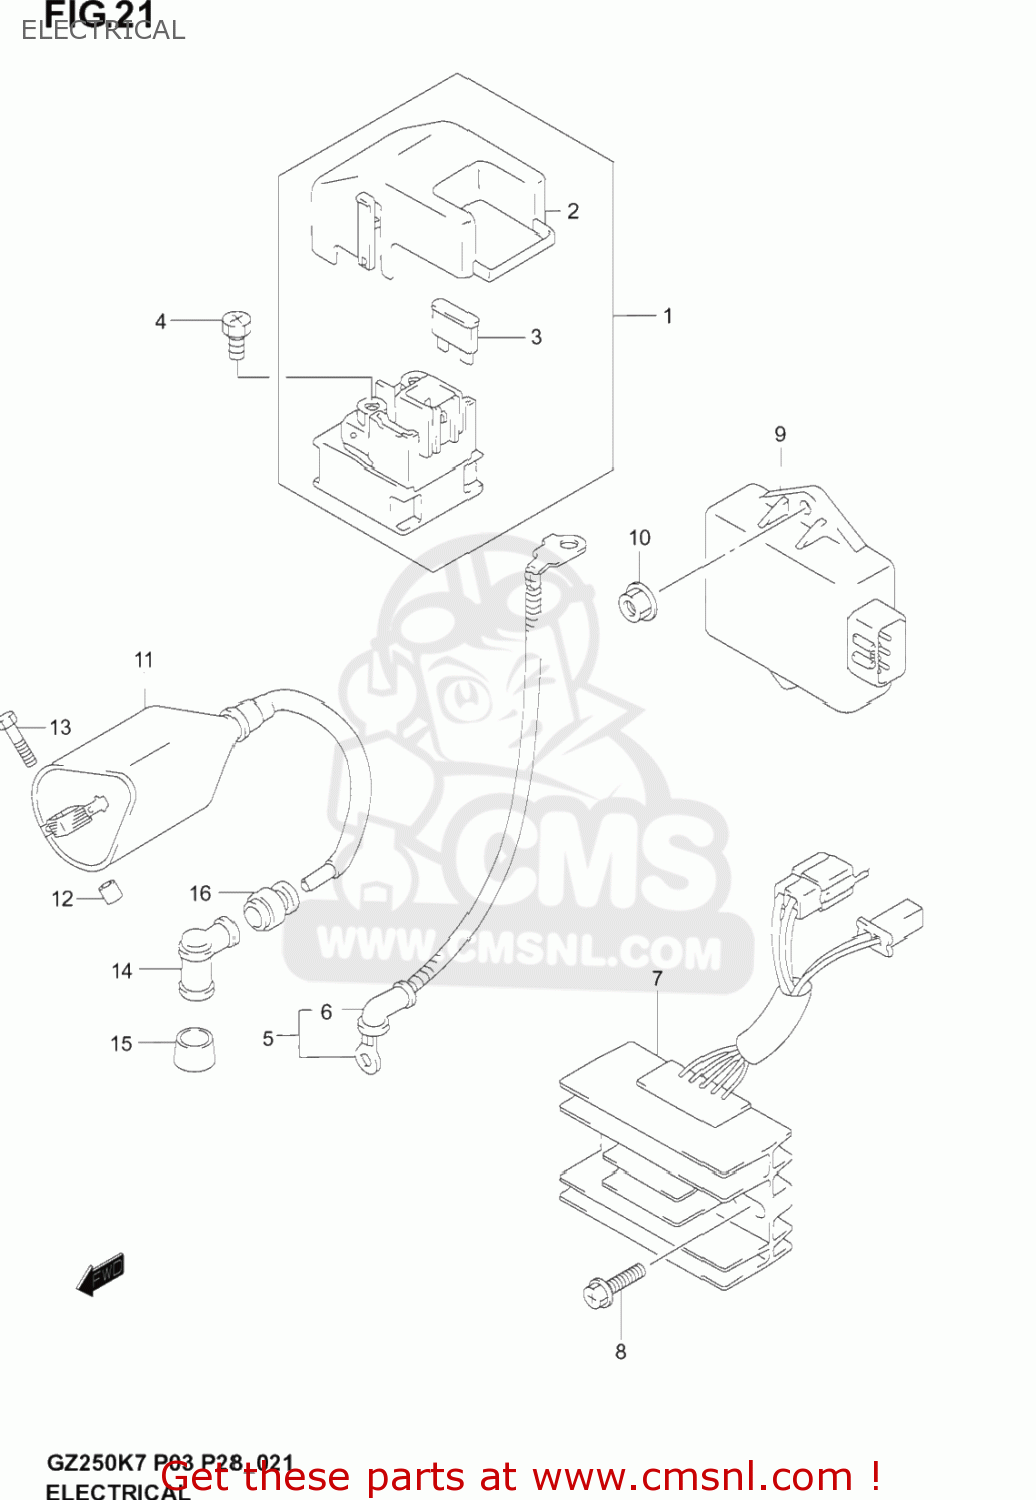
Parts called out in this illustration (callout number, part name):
1	RELAY ASSY, STARTING MOTOR
2	COVER
3	FUSE (20A)
4	SCREW(6X8)
5	WIRE STARTER M
6	CAP, STARTER MOTOR LEAD
7	RECTIFIER ASSY
8	BOLT
9	IGNITOR ASSY
10	NUT
11	COIL ASSY,IGNITION
12	SPACER(6.2X12X14)
13	BOLT
14	CAP ASSY,SPARK PLUG
15	SEAL,SPARK PLUG
16	SEAL,HIGH TENSION CORD
